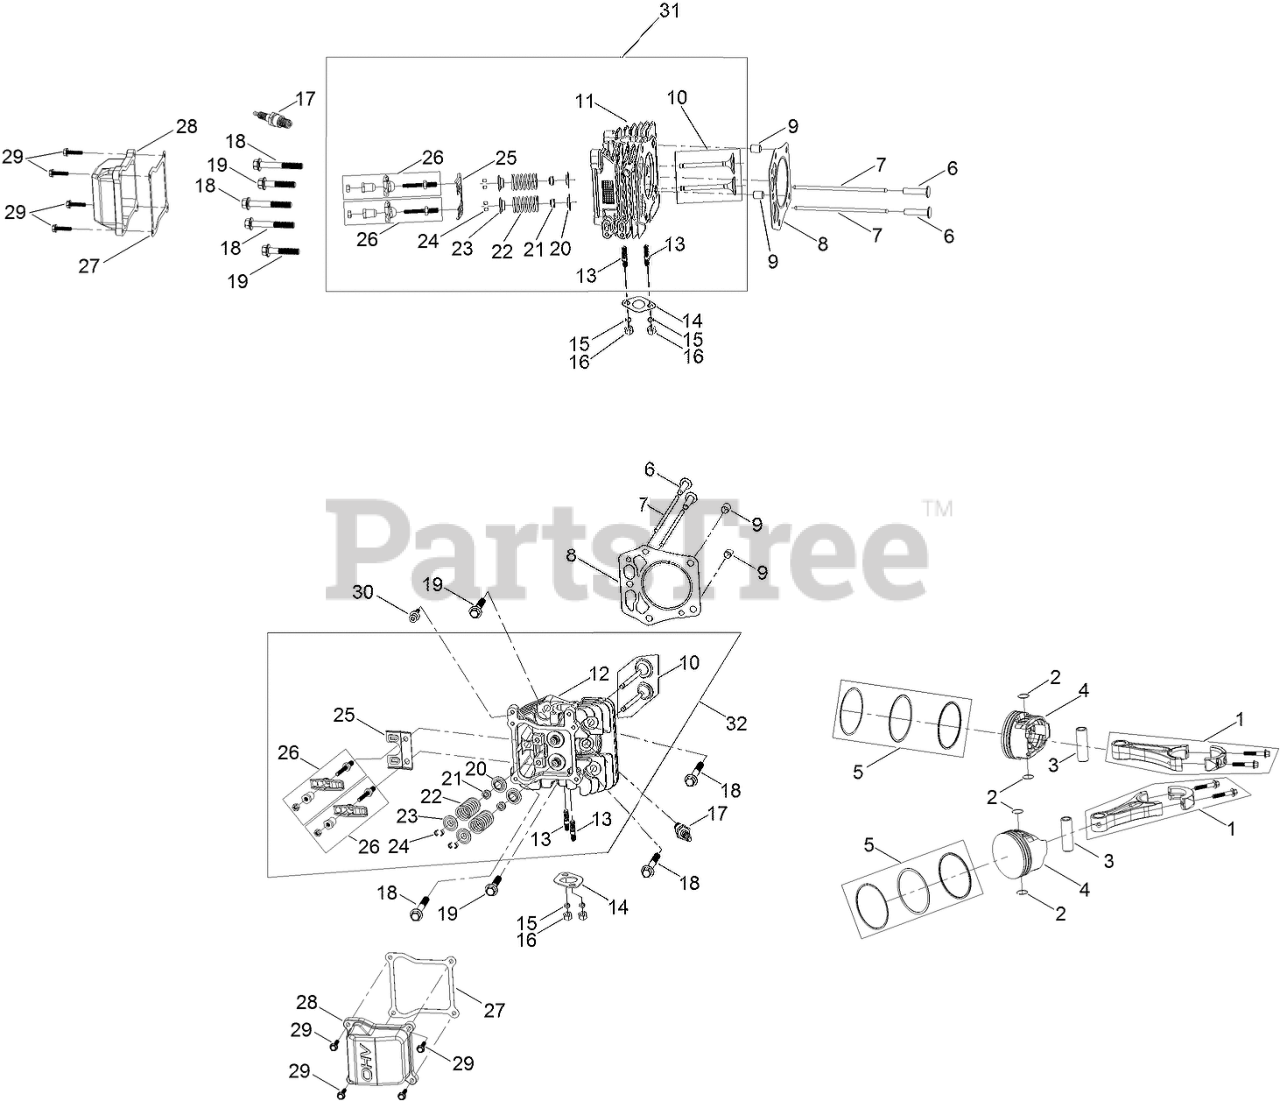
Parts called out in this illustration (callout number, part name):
1	CONNECTING ROD ASM
2	CLIP-PIN, PISTON
3	PIN-PISTON
4	PISTON
5	PISTON RING SET
6	LIFTER-VALVE
7	ROD-PUSH
8	GASKET-HEAD, CYLINDER
9	PIN-DOWEL
10	VALVE SET
11	HEAD-CYLINDER
12	HEAD-CYLINDER
13	STUD-EXHAUST
14	GASKET-EXHAUST
15	WASHER-LOCK, SPLIT
16	NUT-HH
17	SPARK PLUG
18	SCREW-HWH
19	SCREW-HWH
20	SEAT-SPRING, VALVE
21	SEAL-STEM, VALVE
22	SPRING-VALVE
23	RETAINER-SPRING, VALVE
24	KEEPER-VALVE
25	PLATE-GUIDE, PUSH ROD
26	ROCKER ARM ASM
27	GASKET-VALVE COVER
28	COVER-VALVE
29	SCREW-HHF
30	SCREW-SHOULDER, HH
31	RIGHT HEAD ASM
32	LEFT HEAD ASM
